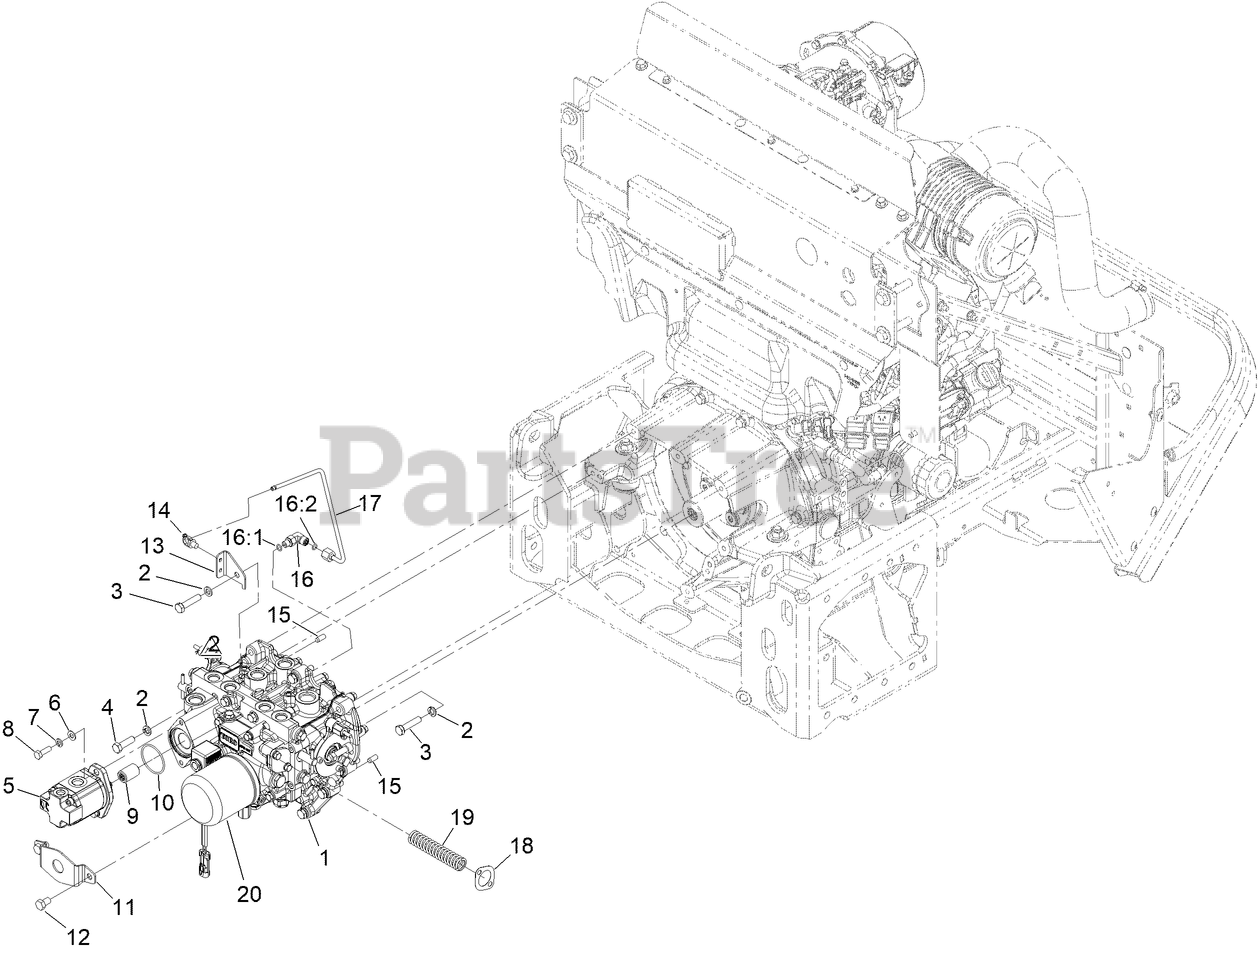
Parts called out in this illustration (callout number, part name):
1	KIT-TRANSMISSION ASM
2	WASHER-LOCK
3	SCREW-HH
4	SCREW-HH
5	HYD GEAR PUMP ASM
6	WASHER-PLAIN
7	WASHER-LOCK
8	SCREW-HH
9	COUPLER-SPLINE
10	O-RING
11	SHIELD-SEAL
12	SCREW-HH
13	SUPPORT-TUBE
14	CLIP-TIE
15	PIN-DOWEL
16	FITTING-ELBOW, 90 DEG
16:1	O-RING
16:2	O-RING
17	TUBE ASM
18	GASKET
19	SPRING-COMPRESSION
20	FILTER-OIL, HYD
